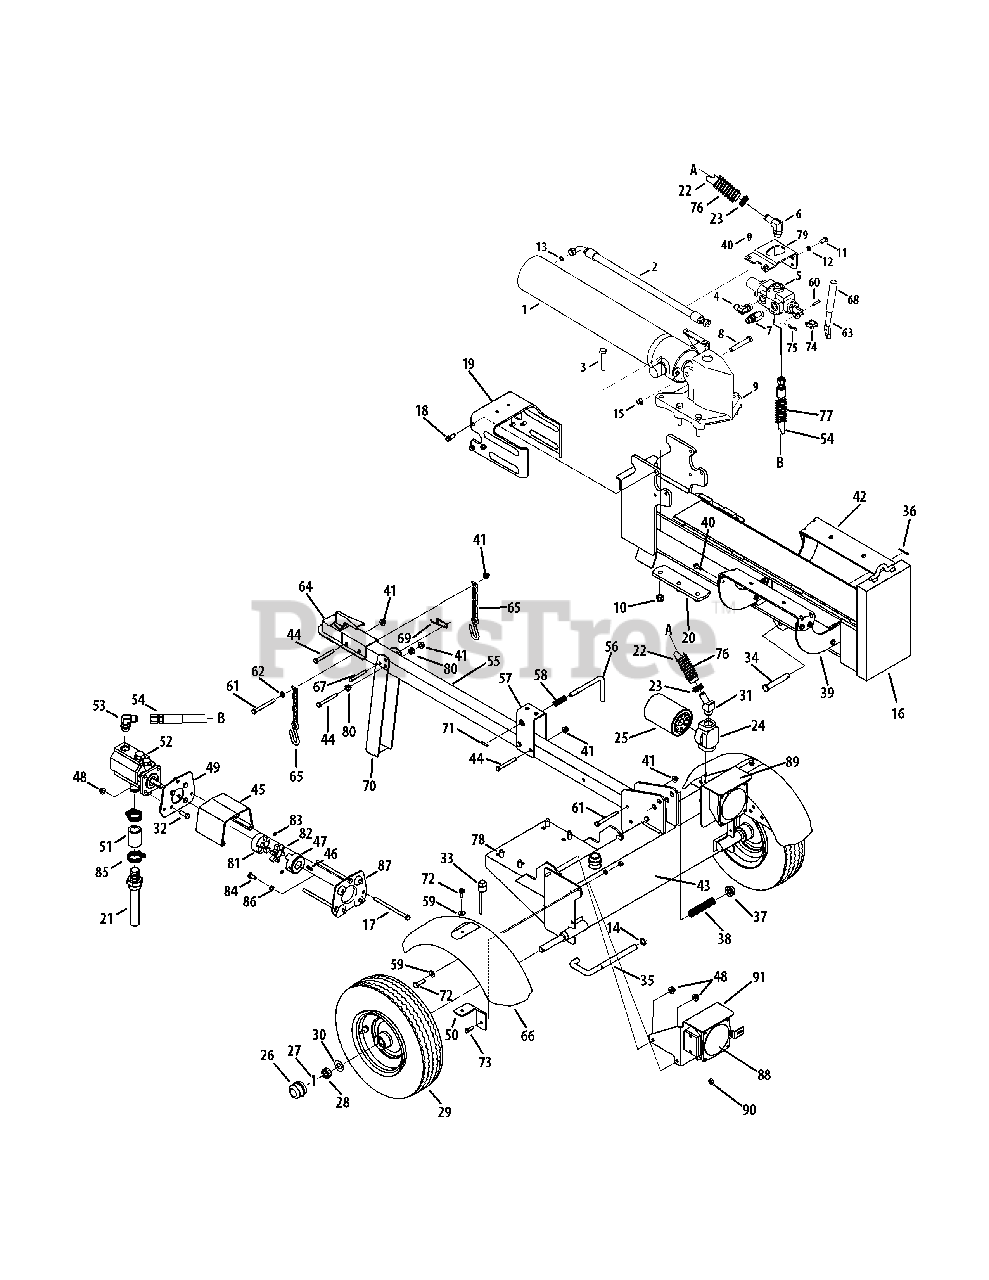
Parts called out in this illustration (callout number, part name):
1	Hydraulic Cylinder
2	Hydraulic Tube
3	Hex Cap Screw, 1/2-20 x 2.75
4	90 Degree Solid Adapter
5	Control Valve
6	Return Elbow
7	Nipple Pipe, 1/2-14
8	Hex Cap Screw, 1/2-13 x 3.25
9	Wedge Assembly
10	Hex Lock Nut, 1/2-20
11	Hex Cap Screw, 3/8-16 x .75
12	Lock Washer, 3/8
13	O-Ring, .468 ID x .078 Dia.
14	Flat Washer, .635 x.93 x.06
15	Hex Lock Nut, 1/2-13
16	Beam Assembly
17	Hex Screw, 5/16-18 x 4.00
18	Self Tapping Screw, 3/8-16 x 1.0
19	Dislodger Bracket
20	Back Plate
21	Inlet Filter
22	Return Hose, 3/4 x 44
23	Hose Clamp, 5/8
24	Filter Housing
25	Oil Filter
26	Hub Cap
27	Cotter Pin
28	Slotted Nut, 3/4-16
29	Complete Wheel Assembly
29	Dust Seal
29	Roller Bearing
30	Flat Washer, .760 x.500
31	Adapter, 3/4-14
31	Hydraulic Fitting, 1 1/16 Orb x .75
32	Hex Screw, 5/16-18 x 1.00
33	Vented Dipstick
34	Clevis Pin
35	Lock Rod
36	Cotter Pin
37	Push Cap
38	Compression Spring
39	Log Tray Bracket
40	Hex Washer Screw, 5/16-18 x .750
41	Flange Lock Nut, 3/8-16
43	Frame Assembly
44	Hex Bolt, 3/8-16 x 3
45	Coupling Shield
46	Square Key, 3/16" x .75
47	Coupling, .750
48	Flange Lock Nut, 5/16-18
49	Rear Coupling Support Bracket
50	Fender Mounting Bracket
52	Gear Pump
53	45 Degree Elbow Fitting
54	High Pressure Hydraulic Hose
55	Tongue Assembly
56	Latch Rod
58	Compression Spring
59	Flat Washer
60	Clevis Pin
61	Hex Cap Screw, 3/8-16 x 3.50
62	Flat Washer, .375 x.738 x.063
63	Hydraulic Valve Control
64	Hitch Coupling Assembly
66	Fender
67	Clevis Pin
69	Spring Pin
70	Jack Stand
71	Spiral Pin
72	Self-Tapping Screw, 5/16-18 x 0.875
73	Self-Tapping Screw, 5/16-18 x 1.00
74	Valve Handle Link
75	Cotter Pin, Bow Tie
76	Hose Guard, 44"
77	Hose Guard, 48"
78	Sems Screw, 3/8-16 x 1.00
79	Outer Valve Bracket
80	Plastic Bushing, .380 ID
81	Coupling, .500
82	Spider Bushing
83	Set Screws
84	Hex Cap Screw, 5/16-24 x .75
85	Hose Clamp
86	Lock Washer, 5/16
87	Front Coupling Support Bracket
88	Light Assembly Kit
89	LH Light Bracket
90	Jam Nut, 3/8-16
91	RH Light Bracket
